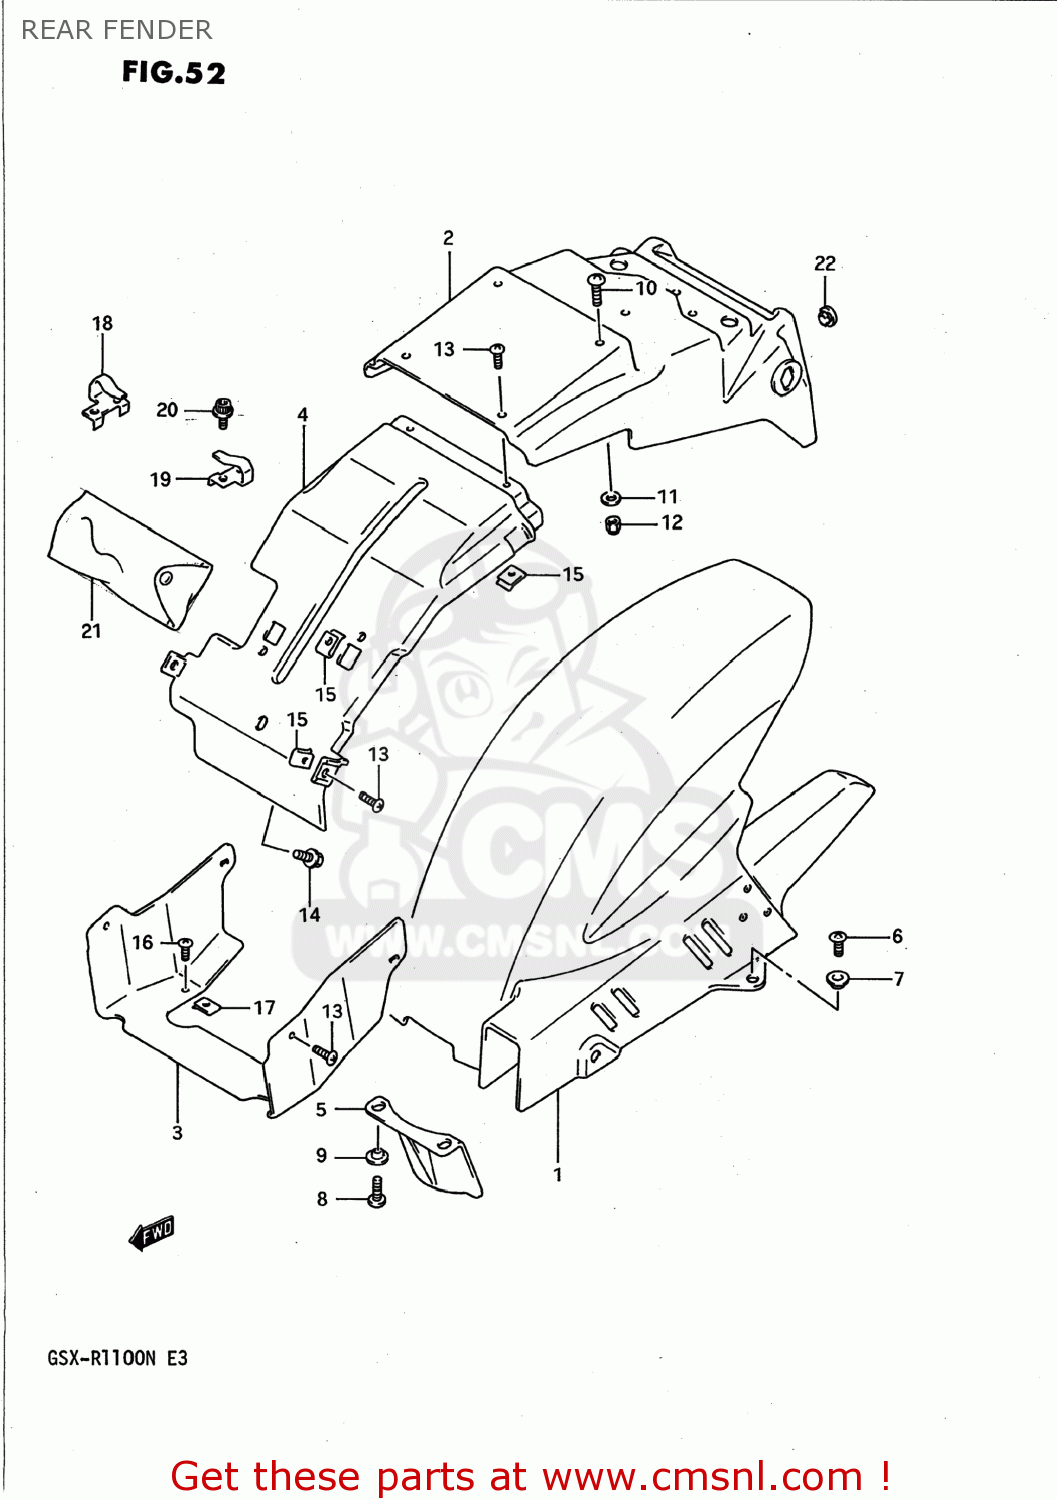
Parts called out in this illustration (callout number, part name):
1	FENDER,RR LWR
2	FENDER,RR UPR
3	FENDER,REAR
4	FENDER,RR UPR FR NO.2
5	GUARD,RR UNIT MUD
6	SCREW
7	WASHER
8	SCREW
9	WASHER,LOCK
10	SCREW
11	WASHER
12	NUT
13	SCREW, FRONT & REAR
14	BOLT
15	NUT,HEADLAMP HOUSING,UPPER
16	SCREW, FRONT & REAR
17	NUT,HEADLAMP HOUSING,UPPER
18	HOLDER,HELMET,R
19	HOLDER,HELMET,L
20	BOLT
21	TOOL SET
22	CAP(OD:16)
